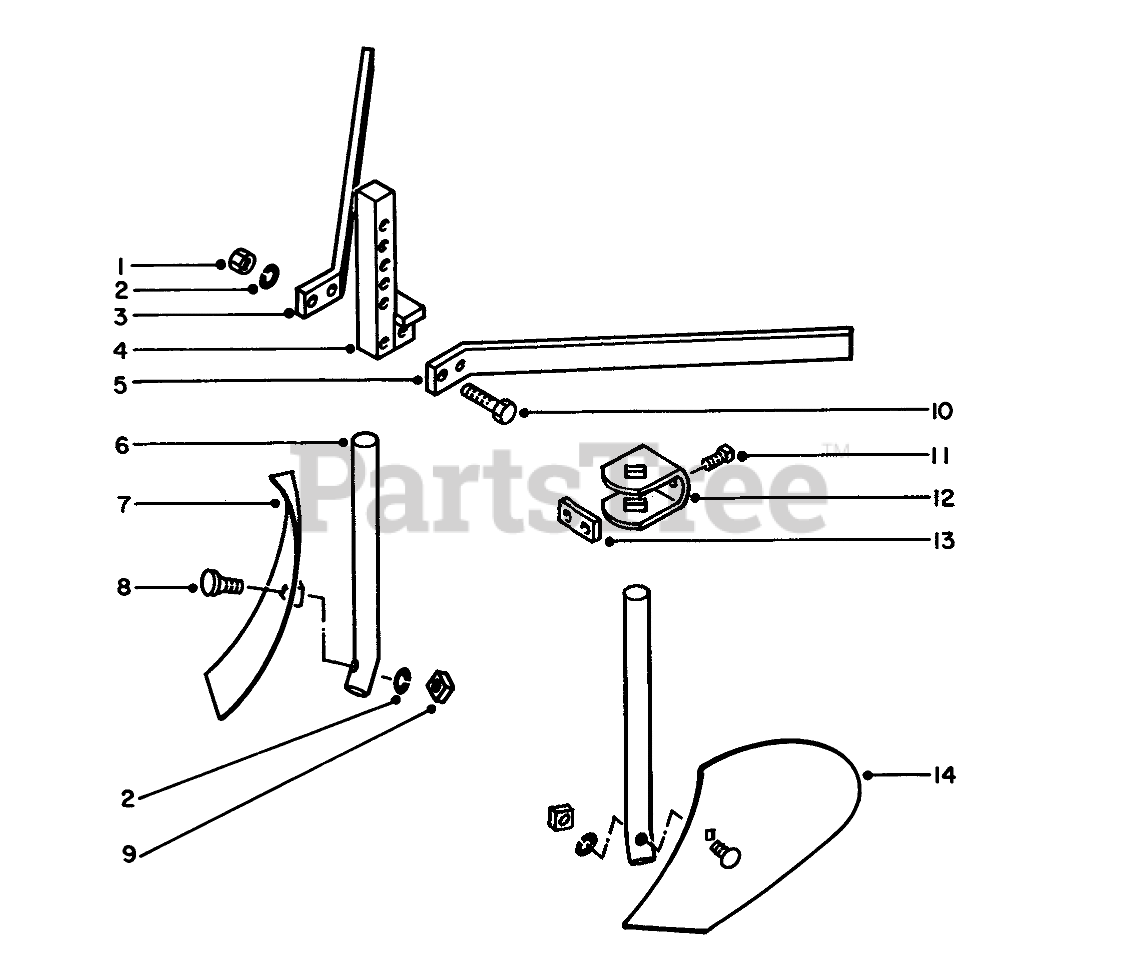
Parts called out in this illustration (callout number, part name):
1	NUT-HEX
2	WASHER-LOCK
3	Hitch Side-A Frame
4	Hitch
5	Attachment Standard
6	Turning Plow-R.H.
7	Plow Bolt
8	Square Nut
9	SCREW-HH
10	Set Screw
11	Clamp
12	Special Nut
13	Plow-L.H.
